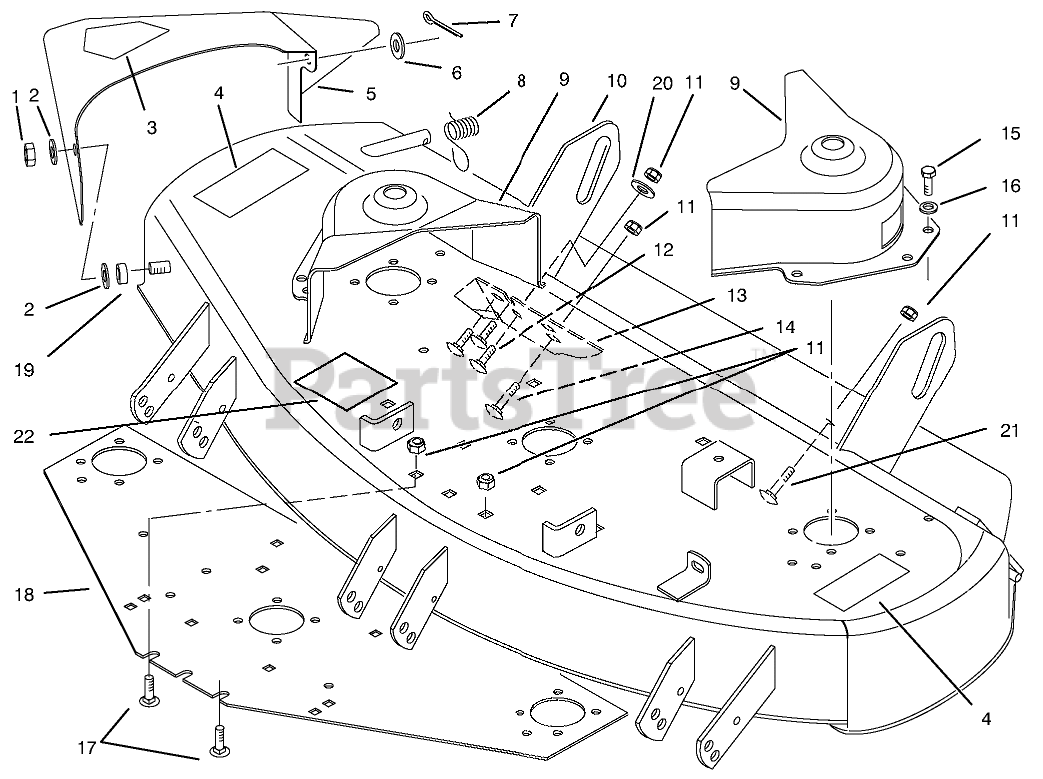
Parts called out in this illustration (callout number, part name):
1	NUT-HJ
2	WASHER
3	DECAL-DANGER
4	DECAL-DANGER
5	Chute Assembly (Incl. Ref. #3)
6	WASHER-FLAT
7	PIN-COTTER
8	SPRING-DEFLECTOR
9	COVER-BELT
10	Deck Assembly (Incl. Ref. #4, 22 & 23)
11	NUT-LOCK, NI
12	SCREW-CARR
13	PLATE-WEAR RH
14	SCREW-CARR
15	SCREW-HWH
16	WASHER-FLAT
17	SCREW-CARR
18	PLATE-DECK
19	BUSHING-PIVOT
20	WASHER-FLAT
21	SCREW-CARR
22	DECAL-BELT INSTALL
